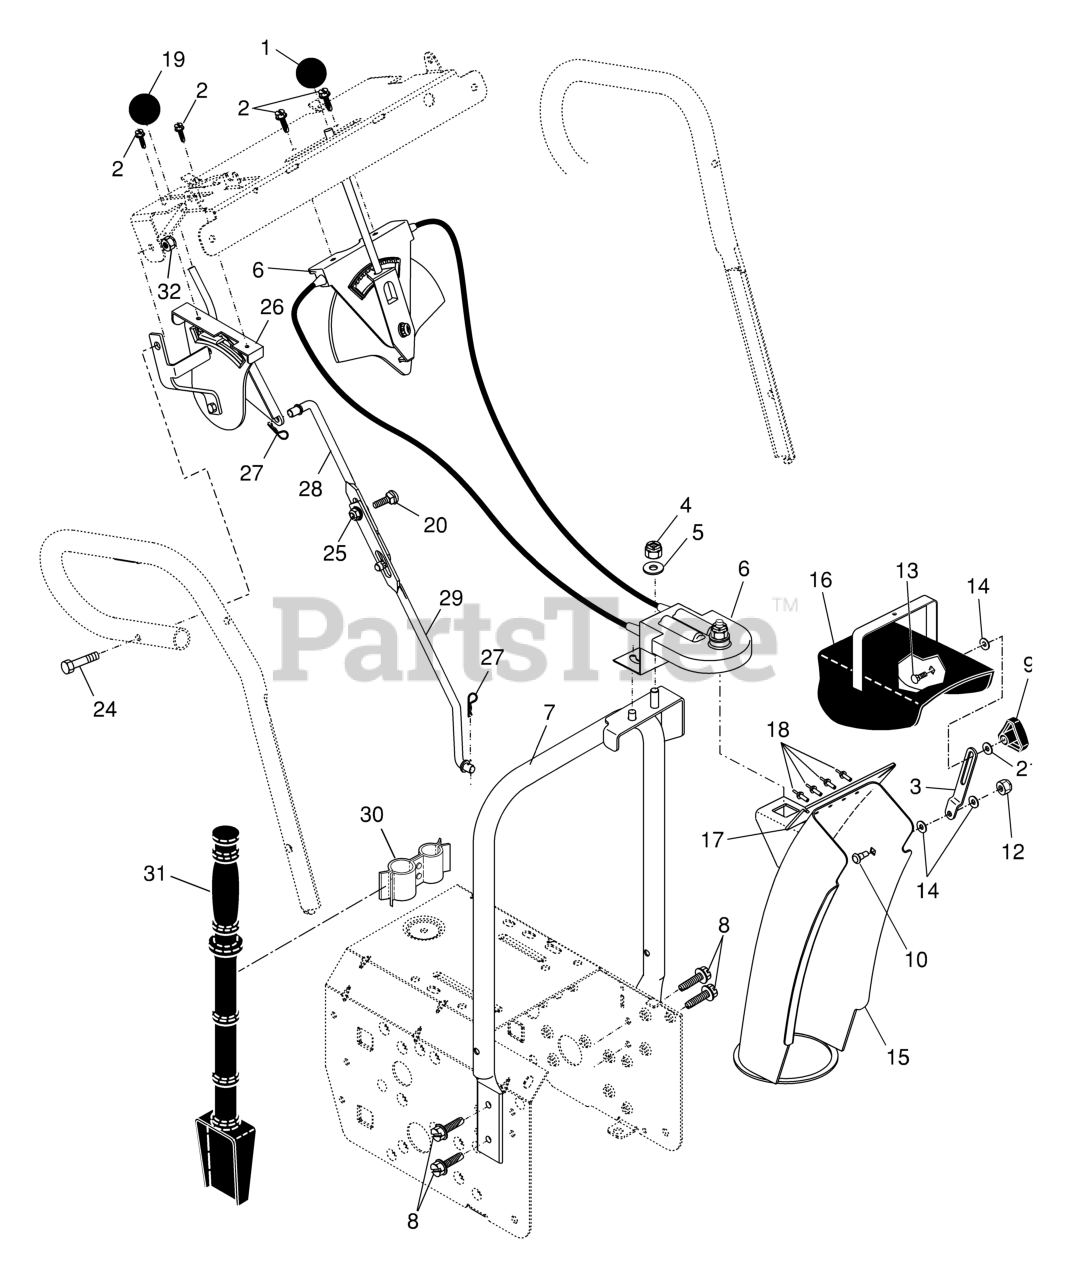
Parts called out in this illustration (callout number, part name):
1	KNOB, LEVER
2	SCREW #10-24 X 5/8
3	STRAP, CHUTE
4	NUT
5	WASHER
6	CONTROL ASSEMBLY,CHUTE ROTATER
7	SUPPORT, PIVOT
8	SELF-TAPPING SCREW 5/16-18X3/4
9	KNOB, DEFLECTOR
10	SHOULDER BOLT
12	NUT.HEX.FLANGE.1/4
13	BOLT
14	WASHER, NYLON FRICTION
15	CHUTE ASSEMBLY
16	DEFLECTOR.WELDMENT.PNT.ORANGE
17	SEAL, DEFLECTOR
18	RIVET BLIND
19	RP KNOB, SPEED CONTROL LEVER
20	BOLT, HEX HEAD
21	WASHER.20X8.5
25	NUT, HEX FLANGE 5/16-18
26	HEAD ASSY SPEED
27	SPRING RETAINER
28	ROD, UPPER SPEED CONTROL
29	ROD, LOWER SPEED CONTROL.SNOW
30	CLAMP.ASM.CLEANOUT.TOOL.SNOW
31	CLEAN OUT TOOL
32	NUT.LOCK.5/16-18
